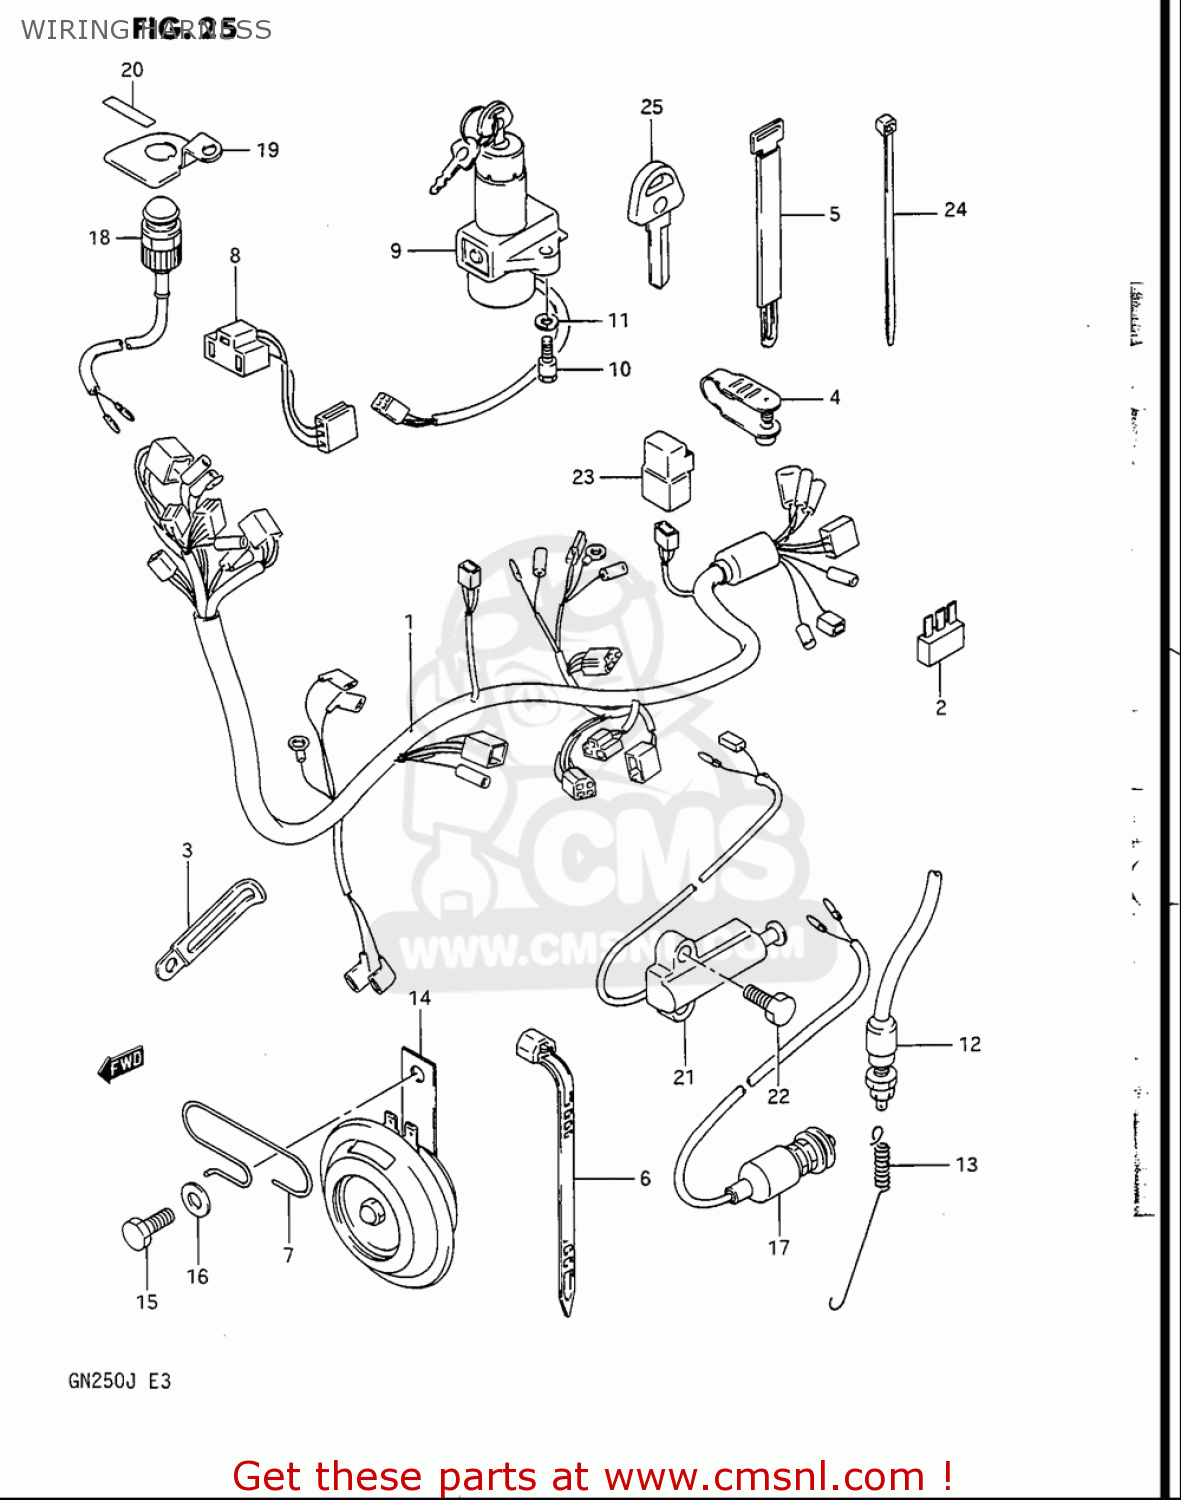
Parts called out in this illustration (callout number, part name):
1	HARNESS,WIRING
2	DIODE(STANLEY DE8804)
3	CLAMP(L:120 T:1.0)
4	CLAMP,L:88
5	CLAMP
6	CLAMP(L:125)
7	GUIDE,WIRING HARNESS
8	LEAD WIRE,HEADLAMP
9	SWITCH ASSY,IGNITION
10	BOLT
11	WASHER,LOCK
12	SWITCH ASSY,STOP LAMP
13	SPRING
14	HORN ASSY
15	BOLT
16	WASHER
17	SWITCH ASSY,SIDE STAND WARNING
21	SWITCH ASSY,SIDE STAND WARNING
22	BOLT
23	RELAY ASSY
24	CLAMP(L:145)
25	KEY,BLANK
